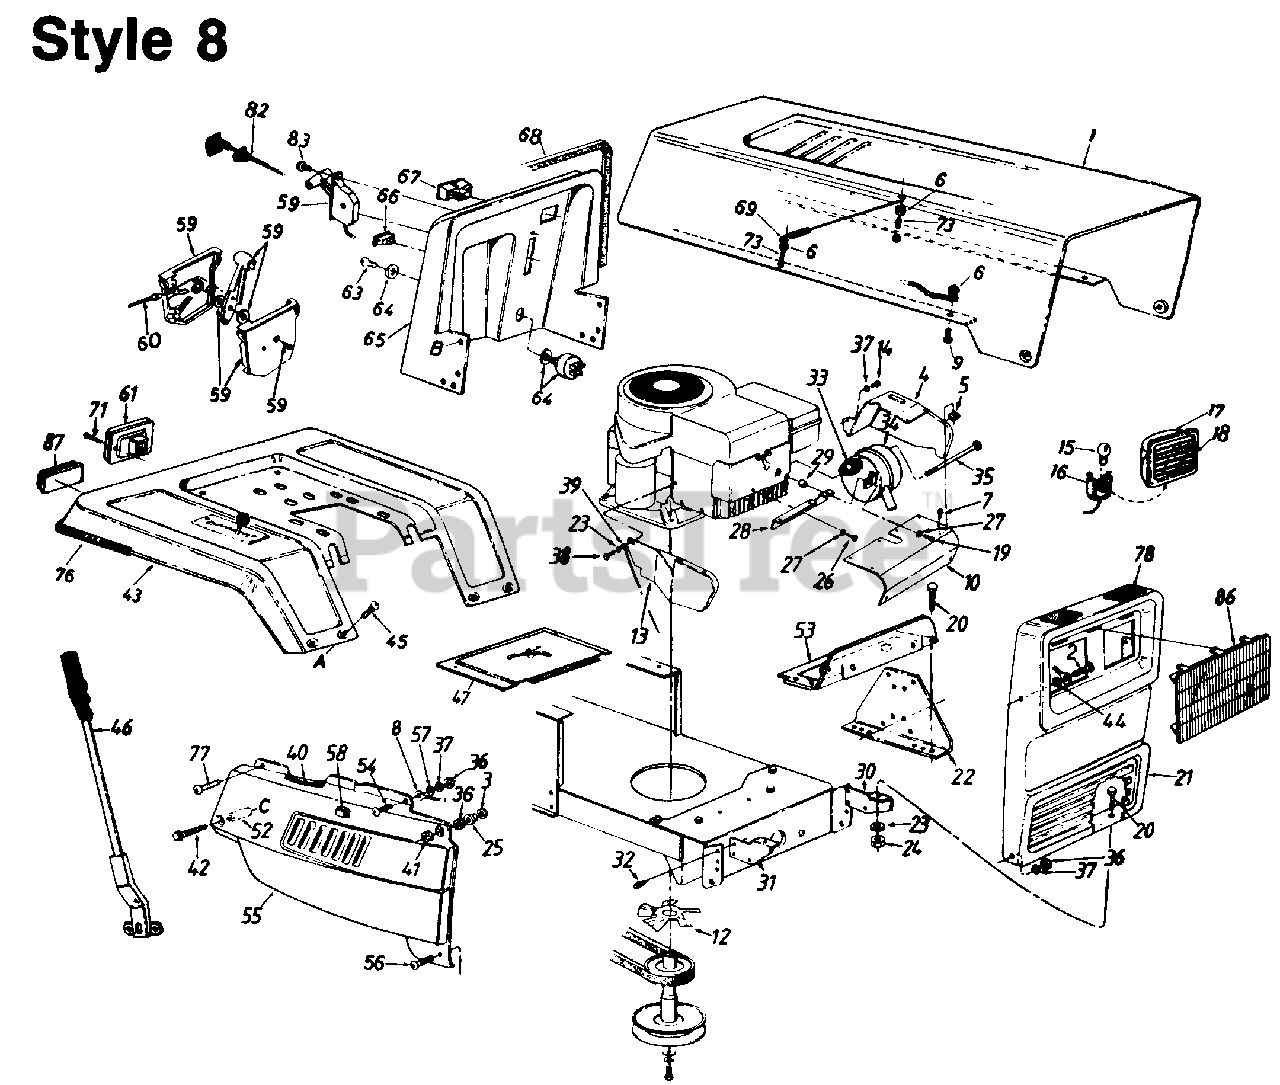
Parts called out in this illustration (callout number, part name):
1	Hood
2	Hex Bolt 1/4-20 x .88" Lg.
4	Muffler Heat Shield-L.H.
5	Speed Nut #10-24 Thd.
6	Hex Sems Nut #10-24 Thd.
7	Hex AB-Tap Scr. #10 x .5" Lg.
8	Hood Stop
9	Truss Hd. Scr. #10-24 x 1/2"
10	Muffler Heat Shield-Front
13	Muffler Heat Shield-R.H.
14	Hex Tap Scr. 1/4-20 x .5" Lg.
15	Bulb
16	Twist Lock-Bulb Socket
17	Headlight Housing
18	Lens
19	Hex Bolt 1/4-20 x .85" Lg.
20	Hex Bolt 5/16-18 x .75n Lg.
23	L-Wash. 5/16" I.D.
24	Hex Nut 5/16-18 Thd .
25	Shld. Spacer
26	Hex Bolt 1/4-20 x 3/8" Lg.
27	Spr. Wash. 1/4" I.D.
28	Heat Shield Bracket
29	Spacer
30	Grille Mount Brkt.-L.H.
33	Exhaust Gasket
34	Muffler
35	Shoulder Bolt
36	Hex Nut 1/4-20 Thd.
37	L-Wash. 1/4" I.D.
38	Truss Mach. Scr. 5/16-18 x .75" Lg.
39	Ground Wire 7.5"
40	Trim Strip-12"
41	Acron Nut 1/4-20 Thd.
42	Hex TT-Tap Scr. 1/4-20 x 1.75" Lg.
44	Ext. L-Wash. 1/4" I.D.
45	Carriage Bolt 1/4-20 x .50"
46	Lift Handle
47	Transmission Panel
52	Spacer 1.30" Lg.
53	Support Brkt.
54	Truss Hd. Scr. 1/4-20 x .75"
55	Side Cover-R.H.
56	Truss Mach. Scr. 1/4-20 x .60" Lg.*
57	Fl-Wash. .281n I.D. x .73" O.D.
58	Mounting Clamp
59	ThroKle Control Box Ass'y.
60	Throttle Control Wire
61	Taillight
63	Ignition Key
64	Ignition Switch
67	Ammeter
68	Trim Strip-31"
69	Hood Spring
71	Truss Hd. AB-Tap Scr. #6 x .62n Lg.
73	Hex Scr. #10-24 x 1.0" Lg.
76	Trim Strip-81"
77	Hex Wash. Hd. Tap Scr. 1/4 x .75" Lg
78	Foam Strip 3/8 x 1-1/8" x 11/2 Lg.
82	Choke Control 29" Lg.
83	Truss Mach. AB-Tap Scr. #10 x .5" Lg.
86	Headlight Bezel
87	Reflector
